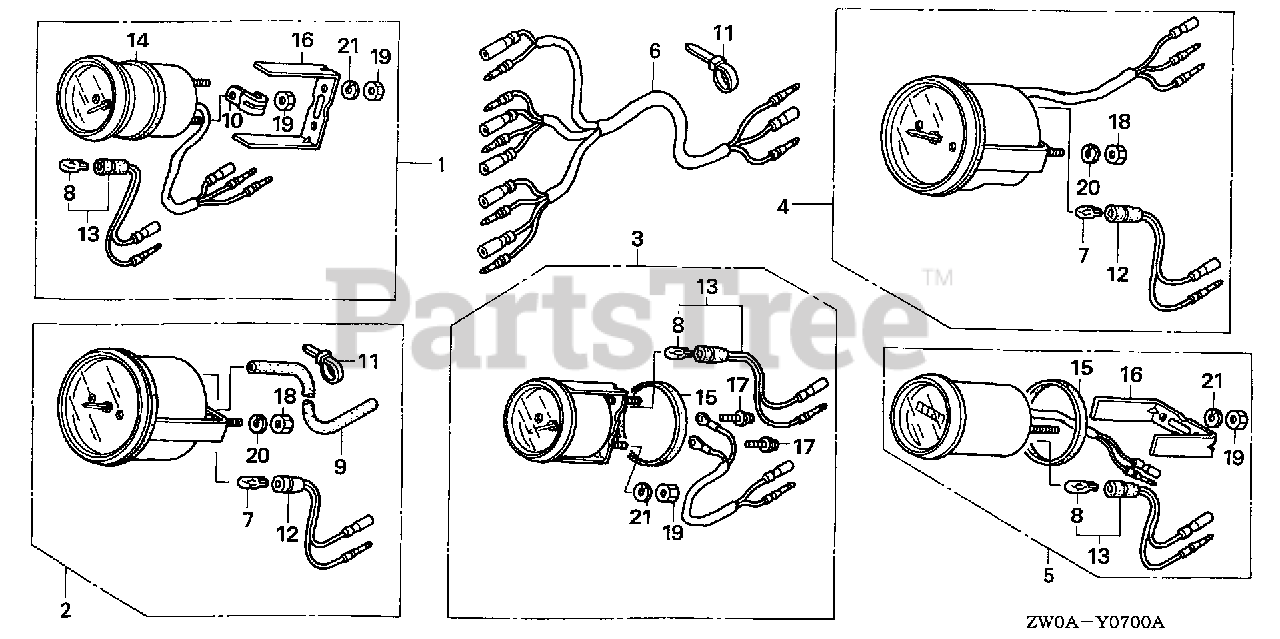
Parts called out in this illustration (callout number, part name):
1	METER KIT, TRIM
1	METER KIT, TRIM (B)
2	SPEEDOMETER KIT
2	SPEEDOMETER KIT *NHA85* (B)
3	METER KIT, VOLT
3	METER KIT, VOLT *NHA85* (B)
4	METER KIT, TACHO
4	METER KIT, TACHO (B)
5	METER KIT, HOUR
5	METER KIT, HOUR *NHA85* (B)
6	HARNESS ASSY., METER (B)
7	BULB, WEDGE BASE (T10)
8	BULB, WEDGE BASE (12V 1.7W)
9	TUBE, SPEED METER (4X7X8000)
11	BAND, SELF-LOCK
17	SCREW-WASHER (3X22)
18	NUT, HEX. (5MM)
19	NUT, HEX. (4MM)
20	WASHER, SPRING (5MM)
21	WASHER, SPRING (4MM)
